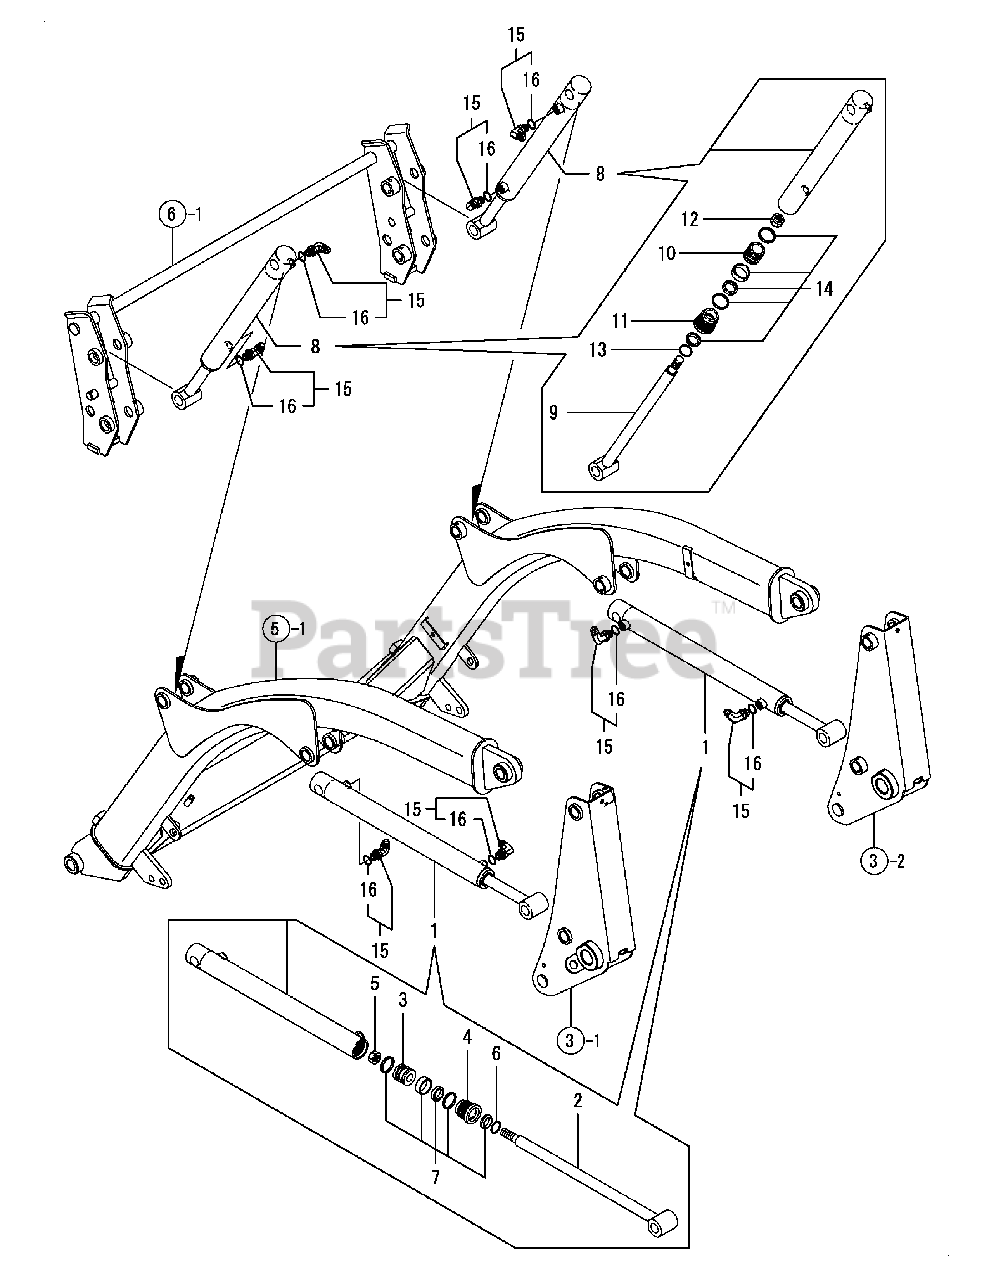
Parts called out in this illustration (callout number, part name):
1	Lift Cylinder Assy
2	Welded Rod CPL, Lift
5	Self Locking Nut
8	Dump Cylinder Assy
9	Welded Rod CPL, Dump
12	Self Locking Nut
15	Joint,90SAE9/16-18
16	Packing, Joint
